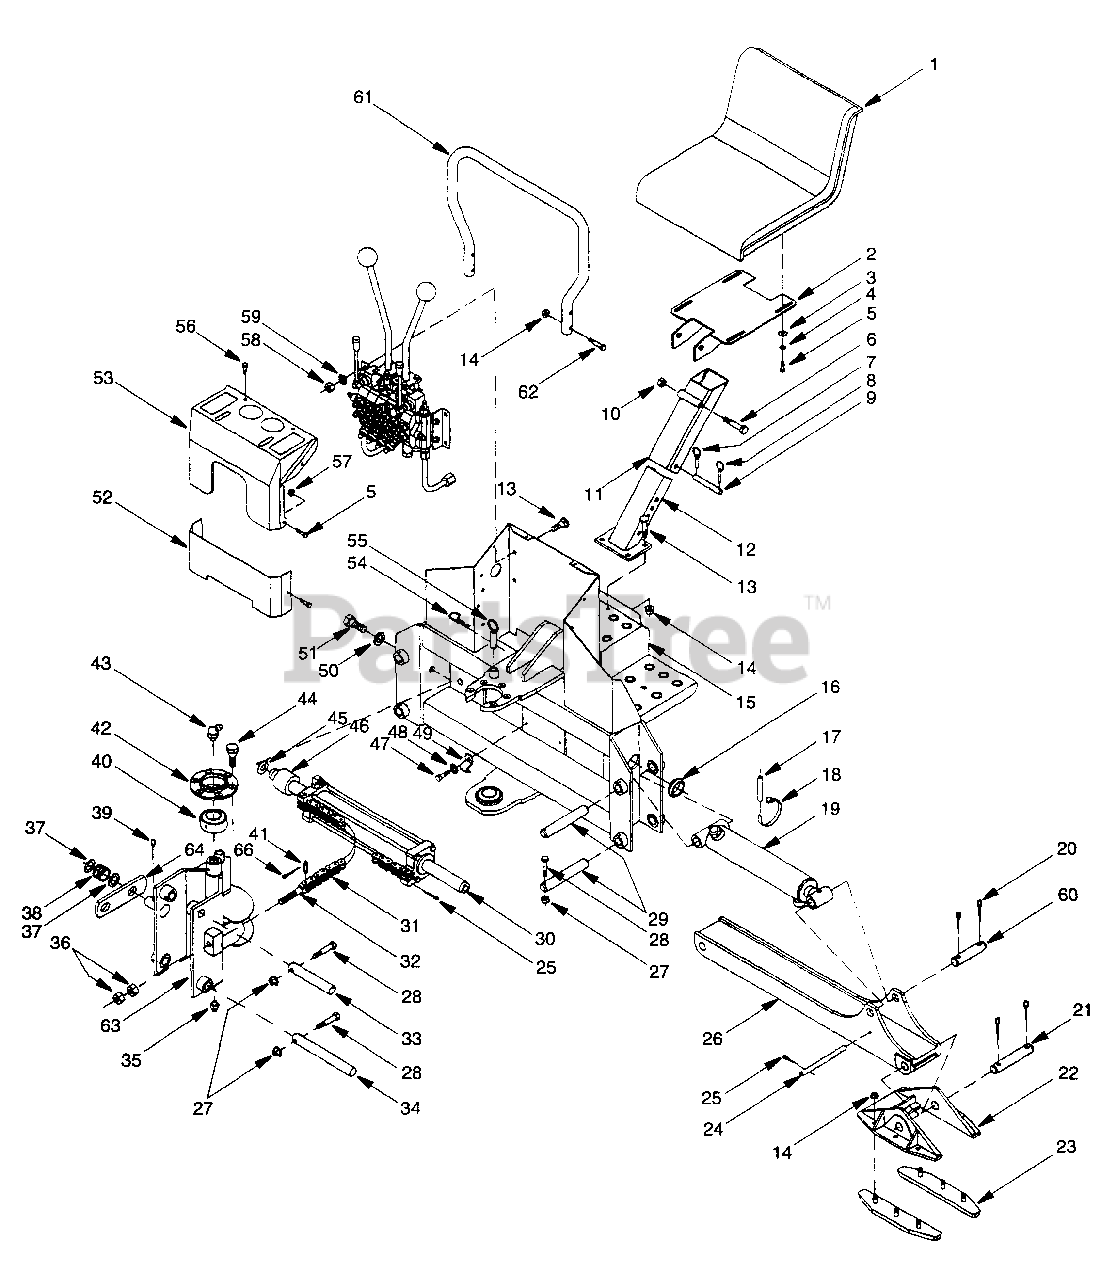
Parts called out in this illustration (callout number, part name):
1	High Back Seat
2	Seat Bracket
3	Flat Washer, 5/16
4	Lockwasher, 5/16
5	Hex Hd Cap Screw, 5/16NC x 3/4 GR5
6	Hex Hd Cap Screw, 1/2 NC x 4 GR5
7	Klik Pin, 3/16 x 1
8	Split Ring, .11 x 1.1 OD
9	Headless Pin, .5 x 3.78
10	Hex Locknut, 1/2 NC
11	Upper Seat Support
12	Lower Seat Support
13	Carriage Bolt, 3/8 x 1 GR5
14	Flange Hex Locknut, 3/8 NC
15	Main Frame
16	Rubber Grommet
17	Hose Protector Shield
18	Hose Clamp, 2.5-3.5
19	Hyd Cylinder, Double Acting 2.5 x 11
20	Cotter Pin, 3/16 x 1.5
21	Headless Pin, 1.0 x 5.84
22	Machined Stabilizer Pad
23	Stabilizer Rubber Pad
24	Headless Pin, .50 x 4.45
25	Cotter Pin, 3/32 x .5
26	Machined Stabilizer Arm
27	Hex Locknut, 1/4
28	Screw, 1/4 x 2.25
29	Drilled Bar,
30	Hyd Cyl, Double Acting 2.5 x 10.63
31	Swing Chain
32	Chain Tension Bolt
33	Pin, 1.Ox 4.55 x6.0
34	Pin, 1.0 x 7.3 x 7.69
35	Tapered Thread Grease Fitting, 1/4-28
36	Hex Nut, 5/8 NC
37	Bushing, 10GA x 1
38	Spring, Compression, 1.19 x .07 x .627
39	Cotter Pin, 1/4 x 1.5
40	Ball Bushing, 1.5 ID
41	Chain Pin, .312 x 1.45
42	Cap Weld Assembly
43	Tapered Thread Grease Fitting, 45° 1/4
44	Wheel Bolt, 7/16 NF x 1.25
45	Shim Washer, 13/16 x .010
46	Bumper, 1.25 x 2.25 x 1.75
47	Hex Hd Cap Screw, 1/4 NC x 3/4 GR5
48	Lockwasher, 1/4
49	Hose Clamp
50	Lockwasher, 3/4
51	Hex Hd Cap Screw, 3/4 NC x 1.5
52	Cover, 11 GA x 5.13 x 12.9
53	Console Cover
54	Safety Pin, 3/16
55	Swing Lock Pin, .62 x 3.31
56	Sheet Metal Screw, .31 x .75
57	Flange Locknut, 5/16 NC
58	Hex Nut, Plated, 3/8 NC
59	Lockwasher, 3/8
60	Headless Pin, 1.0 x 3.80
61	Handle, 1.05 x 13.3 x 15.5
62	Hex Locknut, 7/16 NF
63	Swing Frame
64	Link, .38 x 2.0 x 7.1
